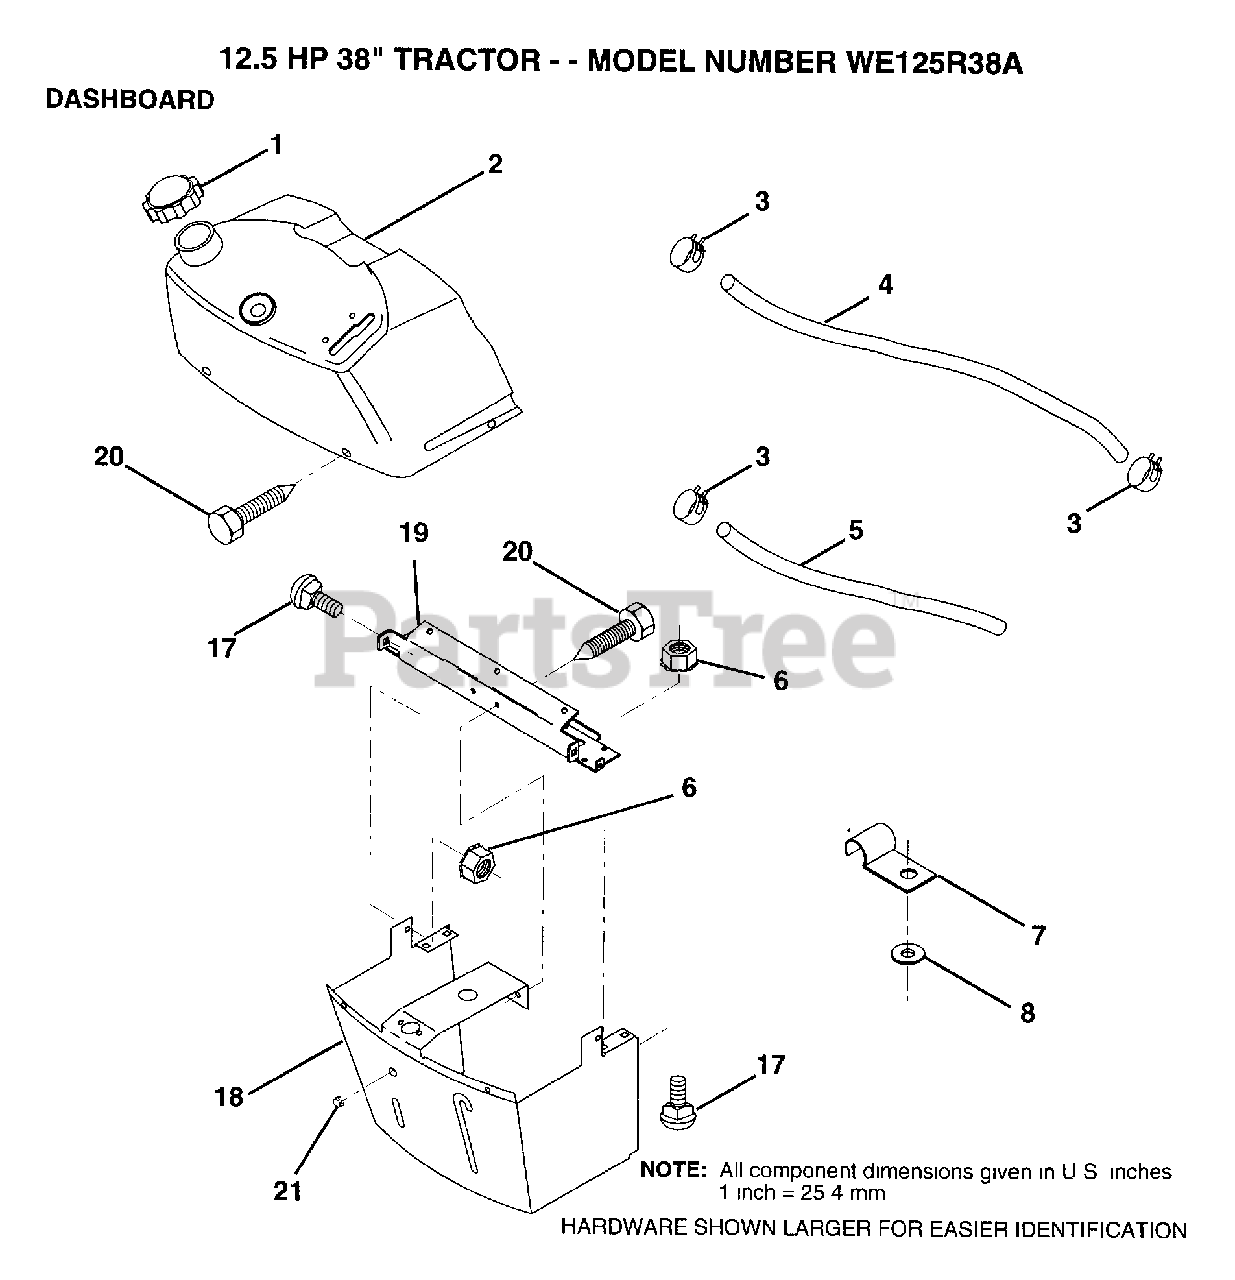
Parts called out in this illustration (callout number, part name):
1	CAP.FUEL.N/VENT
2	TANK.ASM.DASH.LR
3	HOSE CLAMP
5	FUEL LINE T
6	NUT
7	CLIP T
8	WASHER PM
17	BOLT
18	SUPT ASM DASH
19	CROSS BRACE
20	SCREW.1/4-20X1/2
21	PLUG DOME
